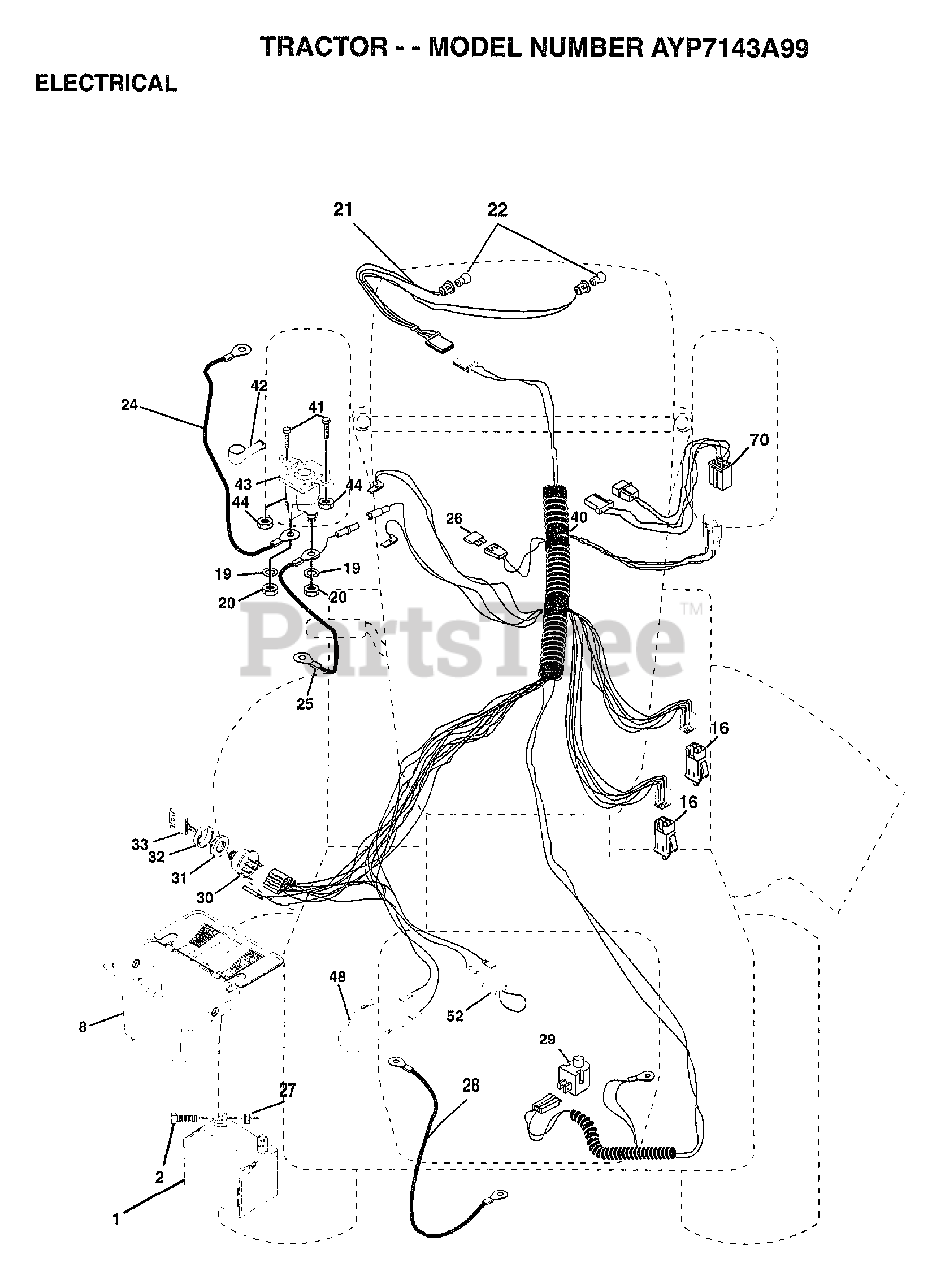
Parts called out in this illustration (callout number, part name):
2	BOLT LT
8	"CASE,BATTERY.MECH"
16	SWITCH INTERLOCK
20	NUT
21	HARNESS.ASM.LIGHT W/4152J
22	HEADLAMP BULB
24	"CABLE T, BATTERY"
25	CABLE.BTRY.6GA.RD
26	FUSE.15 AMP
27	NUT
28	CABLE T
29	SWITCH SEAT
30	SWITCH IGN 4POS
31	NUT IGNITION
32	COVER KEY SWITCH
33	KEY
40	HARNESS
41	BOLT HXHD FIN
44	NUT HXKEP 1/4X20
48	ADAPTER AMMETER
52	PROTECTION LOOP
70	HARNESS.ENGINE.B&S
